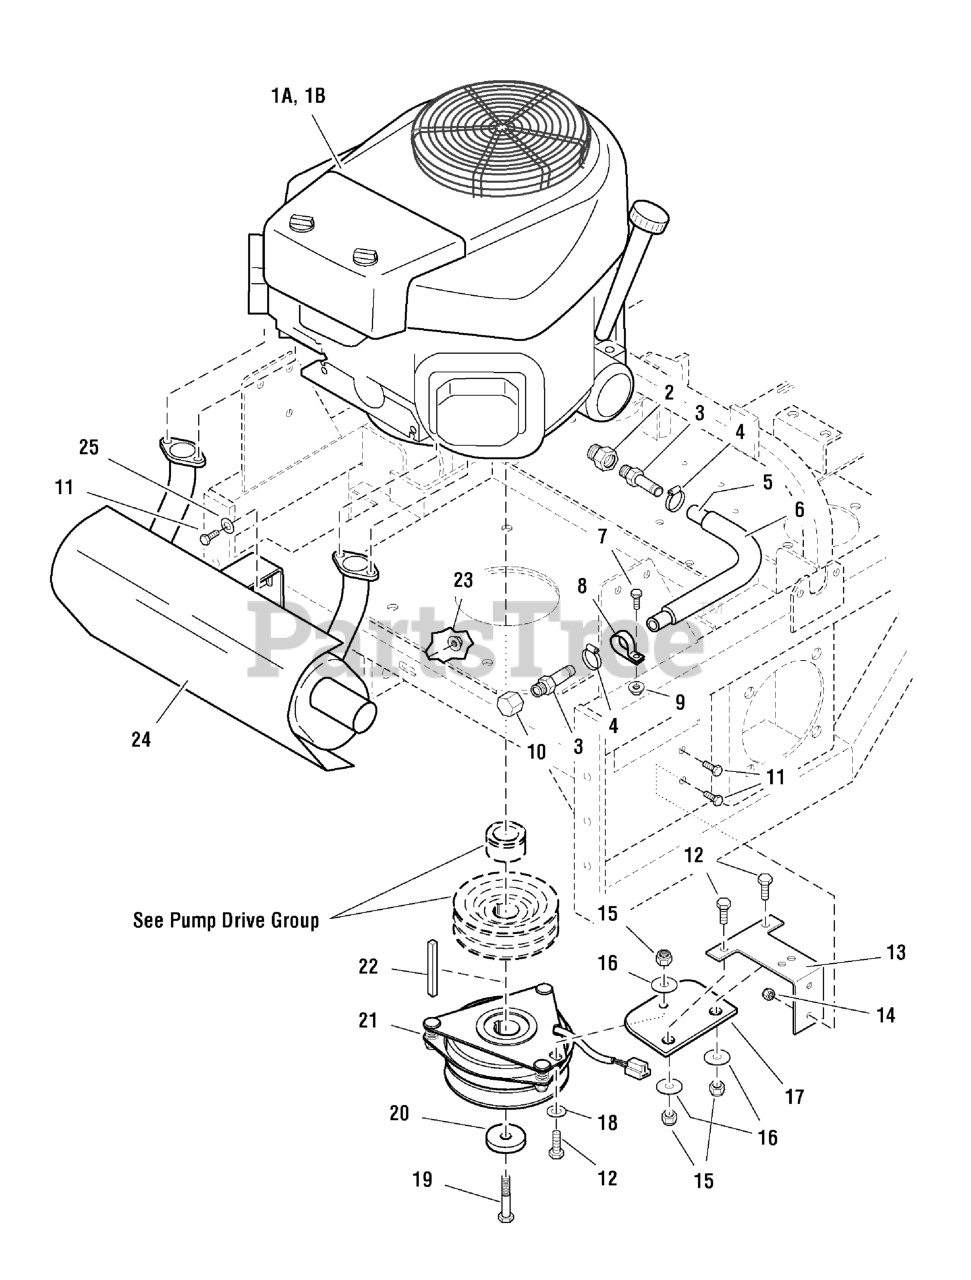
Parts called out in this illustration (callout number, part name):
1B	FUEL FILTER
1B	OIL FILTER (49065-2078)
2	ADAPTER, Oil Drain
3	FITTING, 3/8NPT-1/2" Hose, Straight
4	CLAMP, #6 Hose
5	HOSE, 9"
6	WIRE LOOM, 7"
7	BOLT, 1/4-20 x 3/4
8	CLAMP, Vinyl
9	NUT, 1/4-20 HEX SERR. FLANGE
10	CAP, 3/8 NPT
11	BOLT, 5/16-18 X 3/4 GD5
12	BOLT, 3/8-16 X 1" GD5 CZ
13	CLUTCH ANCHOR
14	NUT, 5/16-18 Hex Nylon Lock
15	NUT, 3/8-16 HEX NYLON LOCK
16	WASHER, 3/8" Fender
17	CLUTCH ANCHOR PAD
18	WASHER, 3/8 SAE
19	CRANKSHAFT BOLT, 7/16 x 2
20	SPACER, .45 x 1.88 x .38
21	ELECTRIC CLUTCH
22	KEY, 1/4 SQ. X 3-1/2
23	NUT, 5/16-18 HEX SERRATED FLANGE (SMALL)
25	WASHER, 5/16" SAE
